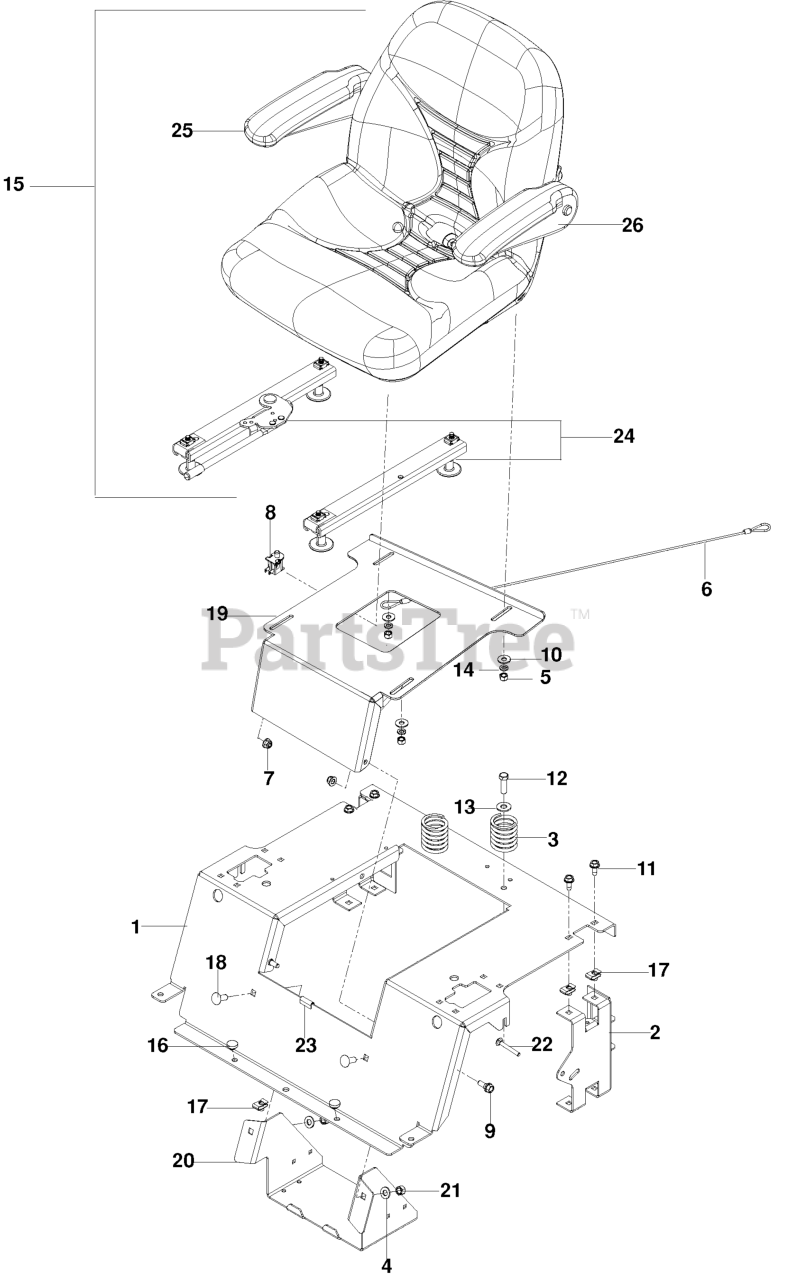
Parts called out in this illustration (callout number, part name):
1	SUPPORT, SEAT, FLAT ORANGE
2	SUPPORT, REAR SEAT, BLACK
3	SPRING, SEAT
4	WASHER 3/8 SAE FLAT
5	NUT 5/16 NYLOC
6	SEAT LANYARD
7	5/16-18 NYLOC FLANGE NUT
8	SEAT SWITCH
9	SB 5/16-18 HEX HD GD5, BLK ZN
10	WASHER 5/16 FLAT
11	BOLT 5/16-18 X 3/4
12	HCS 3/8C X 1 1/4 GR5
13	WASHER 3/8 FLAT
14	WASHER.LOCK.HVY.HLCL.SPR.5/16
15	SEAT
16	GROMMET, BUMPER
17	U-CLIP 5/16-18 NUT RETAINER
18	RHSNB 3/8C X 1
19	PAN, SEAT, ORG
20	BOX, BATTERY, BLACK
21	NUT 3/8-16 NYLOC
22	RHSNB 5/16-18 X 2-1/2 GR5 ZD
24	TRACK ADJUSTMENT KIT
25	ARMREST KIT, RT SQUARE END
26	ARMREST KIT, LT SQUARE END
